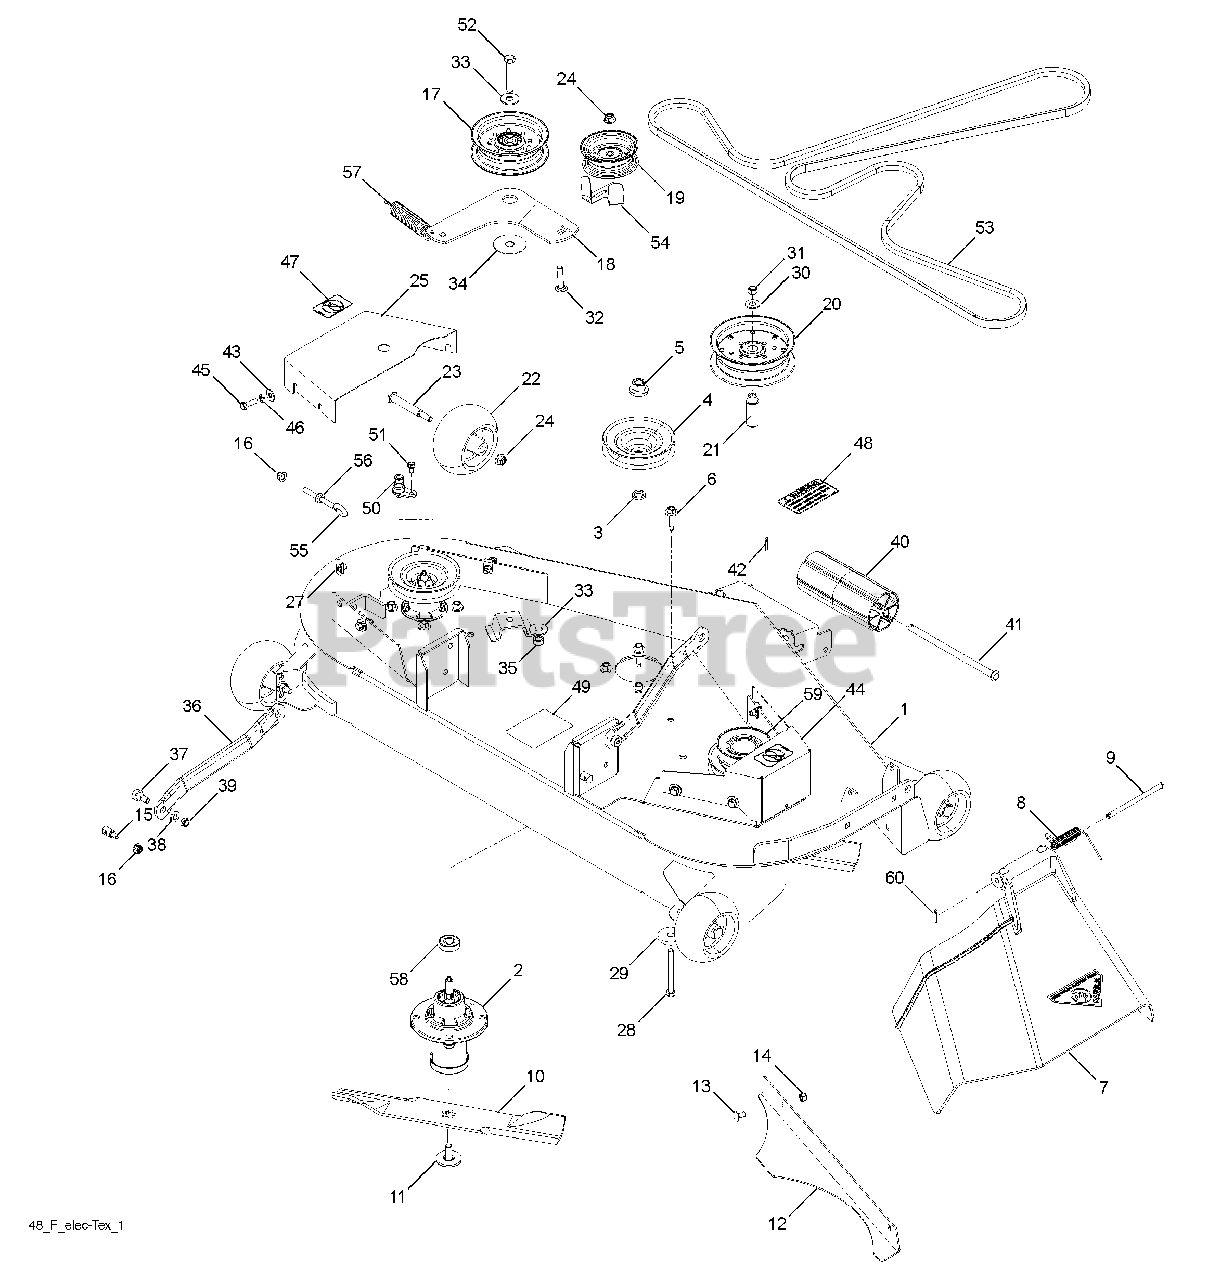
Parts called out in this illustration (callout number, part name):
1	Deck w/ Decals 48"
2	Housing Assembly
3	Washer-Spacer
4	Pulley, Mandrel
5	Nut, 9/16 Top Center Lock
6	Screw, Washer Head
7	Discharge Chute, 48"
8	Spring - Torsion
9	Pin, Clevis 5/16 x 5.19
10	Blade, 16-1/4"
11	Bolt, 7/16, Assy Blade
12	Confinement Plate
13	Rhsnb 5/16-18 x 5/8 Gr 5
14	Nut 5/16-18 Hex Nyloc
15	Stud, Fasten w/ Anti- Rotate
16	Nut 5/16-18 Hex Flange Nyloc
17	Pulley, Idler Spec. Hub
18	Arm, Idler, Blk
19	Pulley, Idler
20	Pulley, Idler
21	Idler Bushing
22	Wheel, Gauge
23	Bolt, Shoulder
24	Nut 3/8-16 Hex Flg Nyloc
25	Shield, Belt LH
27	Retainer 5/16c U Type
28	Hcs 3/8-16 x 3-1/2 Gr 5
29	Heavy Washer
30	Washer, 3/8 Flat Std
31	Nut 3/8-16 Hex Nyloc
32	Rhsnb 3/8-16 x 1-3/4 Gr 5
33	Washer, 7/16 Flat
34	Washer, Flat Hardened
35	Nut, 7/16-14 Hex Nyloc
36	Arm, Susp., Rear
37	Sb 3/8-16 x 3/8 Skt Hd
38	Washer, 3/8 Sae Flt
39	Nut, 3/8-16 Hex Jam Nyloc
40	Roller, Nose, 48"
41	Rod, Roller, Nose, Narrow
42	Clip Reatainer 0.375
43	Washer, 5/16 Std Flt
44	Shield, Belt Rh
45	Hcs 5/16-18 x 1 Gr 5
46	Wash 5/16 Slw
47	Decal, No Step
48	Decal, Warning
49	Decal, Deck Sch
50	Washout Port
51	Bolt, 1/4-20 x 1/2
52	Hcs 7/16-14 x 2-1/2 Gr 5
53	Belt, Deck
54	Guard, Belt
55	Eyebolt 5/16 x 3-1/2
56	Nut 5/16-18 Hex Whizlk
58	Ball Bearing
59	Pulley
60	Clip Retainer Dia. 290
